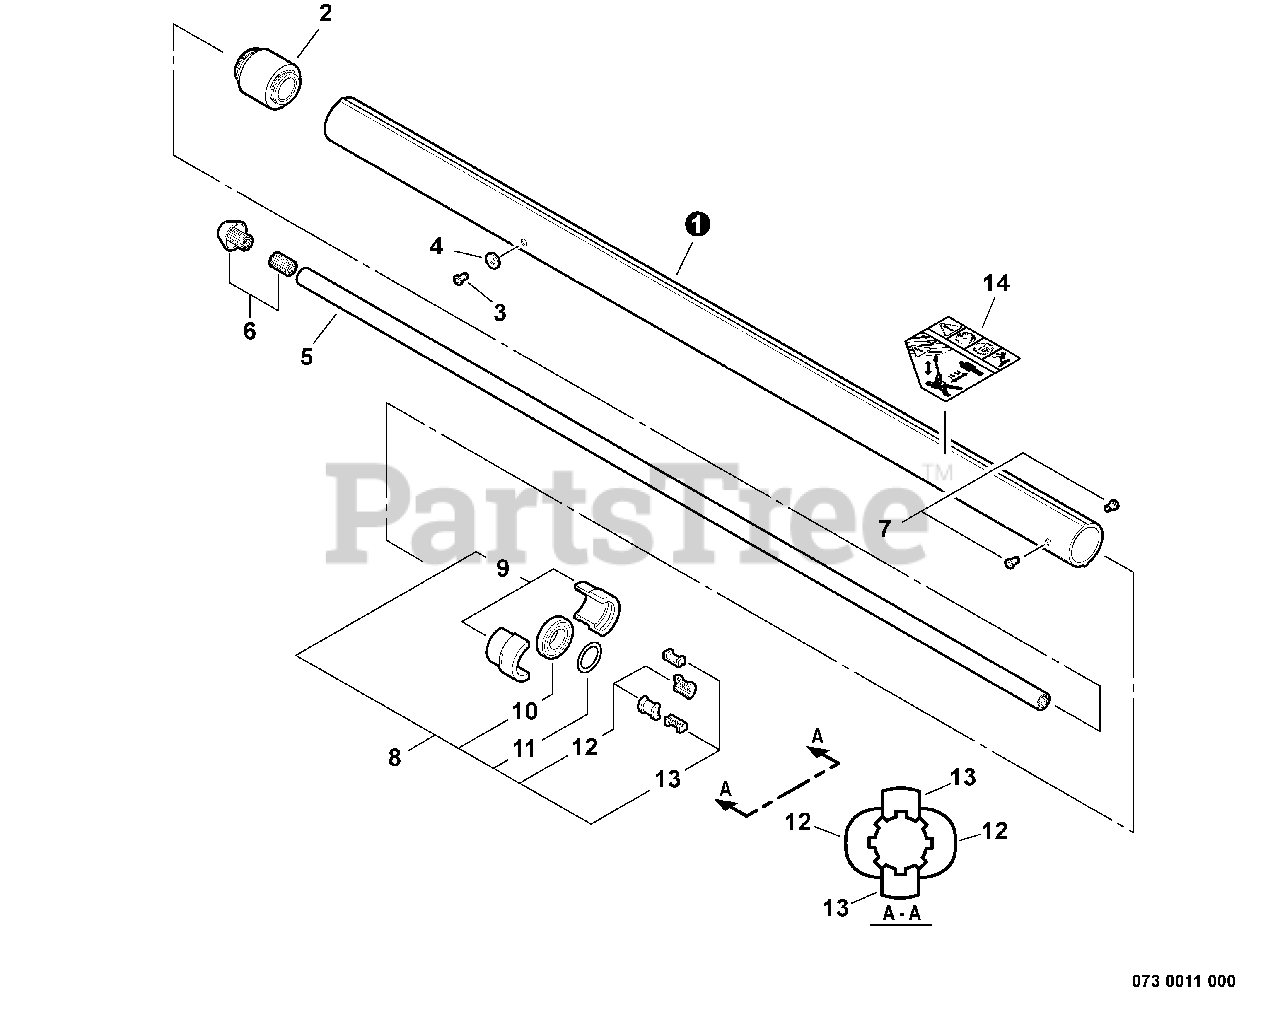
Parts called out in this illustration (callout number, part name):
1	PIPE, MAIN - BLACK
2	GUIDE, SHAFT
4	WASHER - 5
5	DRIVESHAFT - UPPER
6	ADAPTER, DRIVESHAFT - UPPER
8	BEARING HOLDER KIT
9	BEARING HOLDER KIT
10	BEARING, BALL - 6002
11	WASHER - SPRING
12	HOLDER, INNER BEARING - LARGE
13	HOLDER, INNER BEARING - SMALL
14	LABEL - CAUTION
